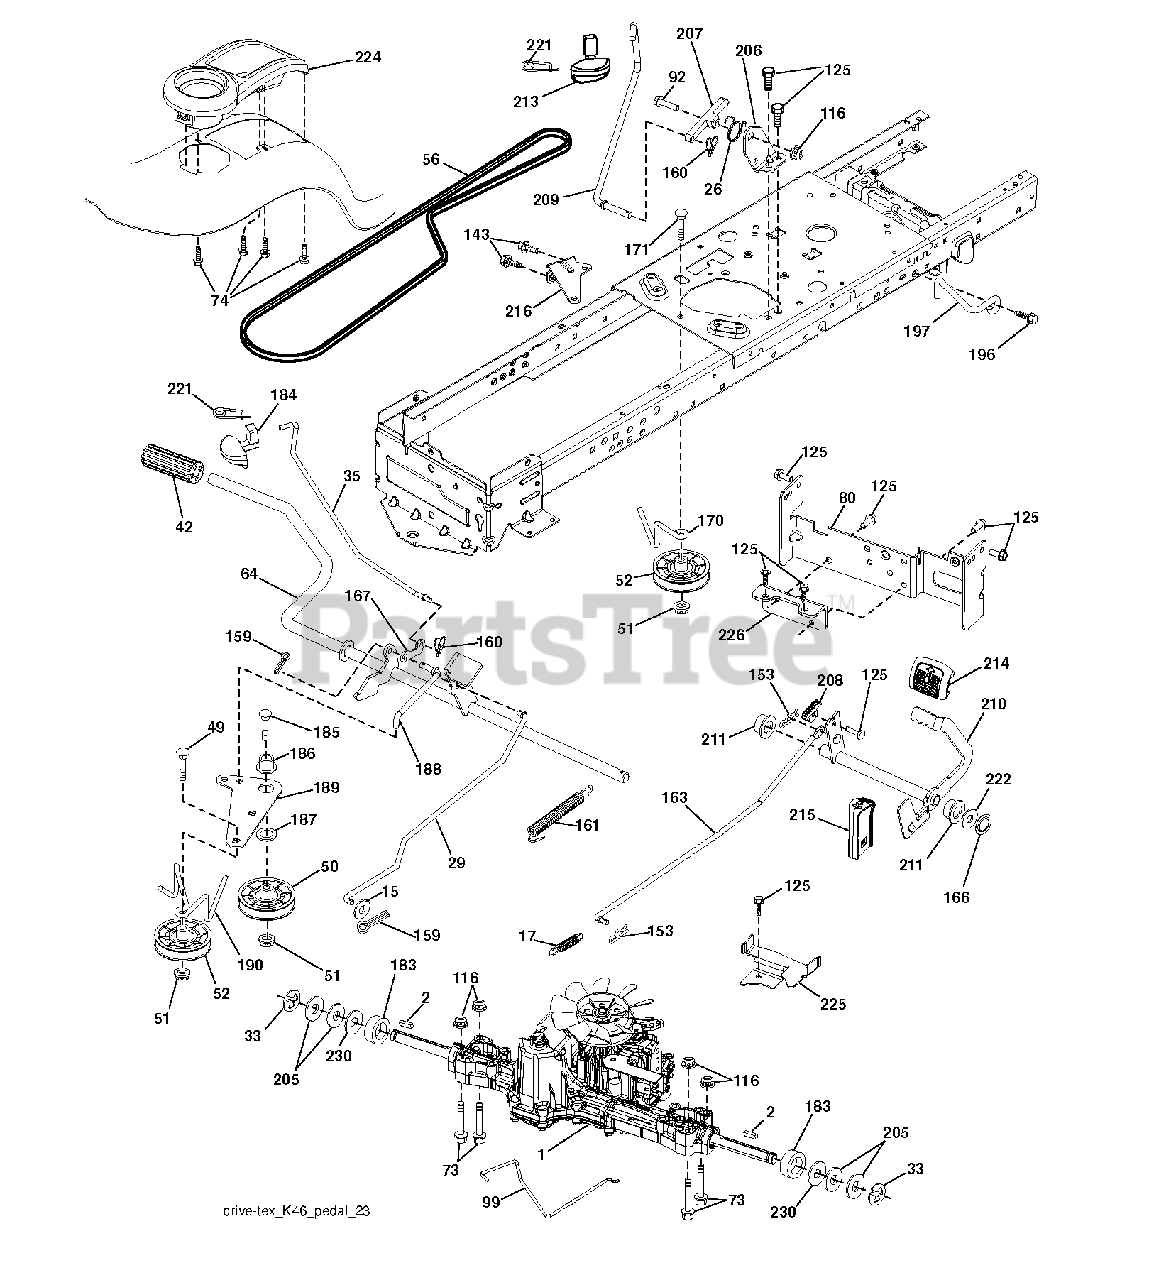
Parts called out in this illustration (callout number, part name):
2	SQUARE KEY
17	SPRING.BRAKE.K46.GREEN
26	SPRING.RETURN.CRUISE
29	ROD.BRAKE.K46
33	E-RING LT
35	ROD.BRAKE.PARKING.GT.H
42	PEDAL COVER T
49	BOLT
50	IDLER.FLAT.910.OFFSET
51	NUT LOCK FLG 3/8-16 UNC
52	IDLER.V-GROOVE.910.OFFSET
64	SHAFT.ASM.PEDAL.BRK.CNTR
73	BOLT HEX 5/16-18 GR 5
74	SCREW.HI-LO.CONSOLE
80	STRAP TORQUE
92	BOLT
99	ROD.SPRING.BYPASS.K46.LT.Z
116	NUT LOCK HEX FLANGE 5/16-18
125	SCREW
153	RETAINER M
159	COTTER PIN
160	RETAINER CLIP
161	SPRING, RETURN LT
163	ROD.CONTROL.PEDAL.K46
166	NUT.PUSH.625.2006
167	LATCH.BRAKE.SPRING
170	KEEPER.V-IDLER.CENTER.
171	BOLT
183	SPACER AXLE
184	HANDLE.PARKG.BRK.HUSQ/
186	SPACER.RETAINER
187	WASHER 12/32X2X10GA
188	LINK.CLUTCH.GROUND.DRIVE
189	BELLCRANK.GROUND.DRIVE.TEX.
190	KEEPER.BELLCRANK.DRIVE
196	SCREW 3/8-16X1
197	LINK.CLUTCH.ANIT-ROTAT
206	BRKT.MOUNT.LATCH.CRUIS
207	LATCH.CONTROL.CRUISE
208	GEAR.SECTOR.CONTROL.CR
209	ROD.CONTROL.CRUISE.GT.
210	ROCKER.ASM.PEDAL.CONTR
211	BEARING.NYLON
213	KNOB.CONTROL.CRUSIE.HU
214	PAD PEDAL FORWARD
215	PEDAL.REVERSE.TEX.GT.4
216	BRACKET.PULLEY.IDLER.W/TEX
221	RETAINER.SPRING.CLIP.H
222	WASHER 21/32 X 1-1/4 X 10 GA.
224	CONSOLE.TOOLBOX.PCH.ERGO.BLACK
225	KEEPER.BELT.TRANSAXLE.K46
226	BRACKET.MOUNT.TORQUE.K46.TLT
230	WASHER.HARDENED
